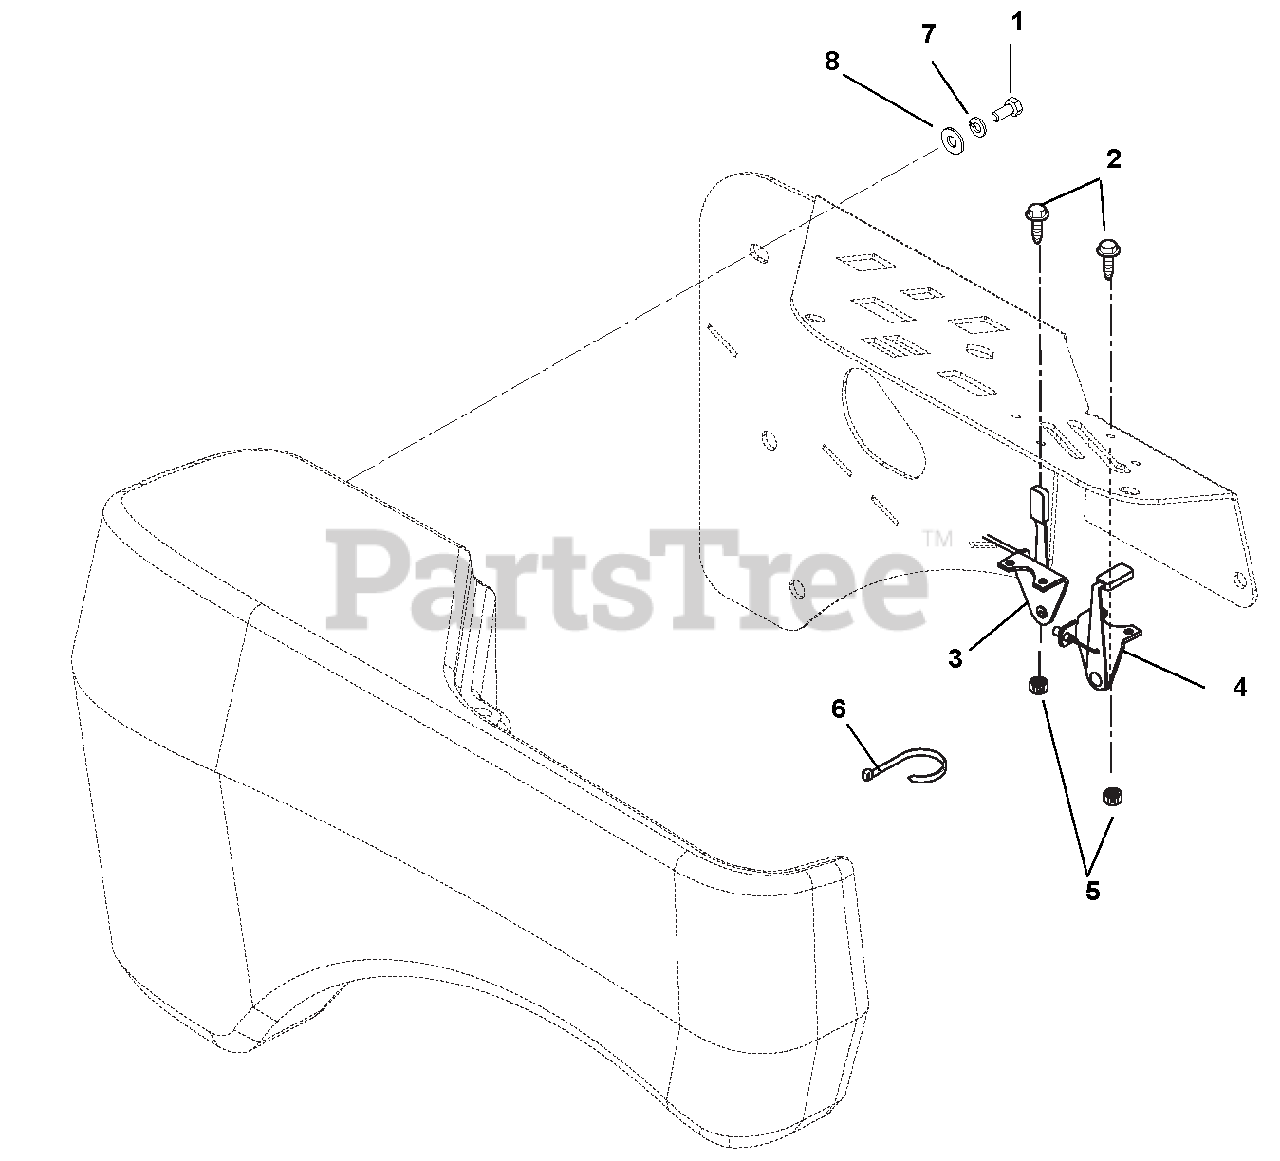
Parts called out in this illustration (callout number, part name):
1	@BLT-HEX .31-18X.75 GR5 YWZC
2	@SCR-MCH 10-24X.50 HWH YWZC
3	CABLE, THROTTLE-KOHLER (OFM)
4	CHOKE CABLE KOHLER (OFM)
5	NUT-LK-NYL 10-24 W/INSRT YWZC
6	CABLE TIE LG 5-1/2
7	@WSHR-LK .31X.078 REG YWZC
8	WSHR-FL-STL.38X.875X.083 YWZC
